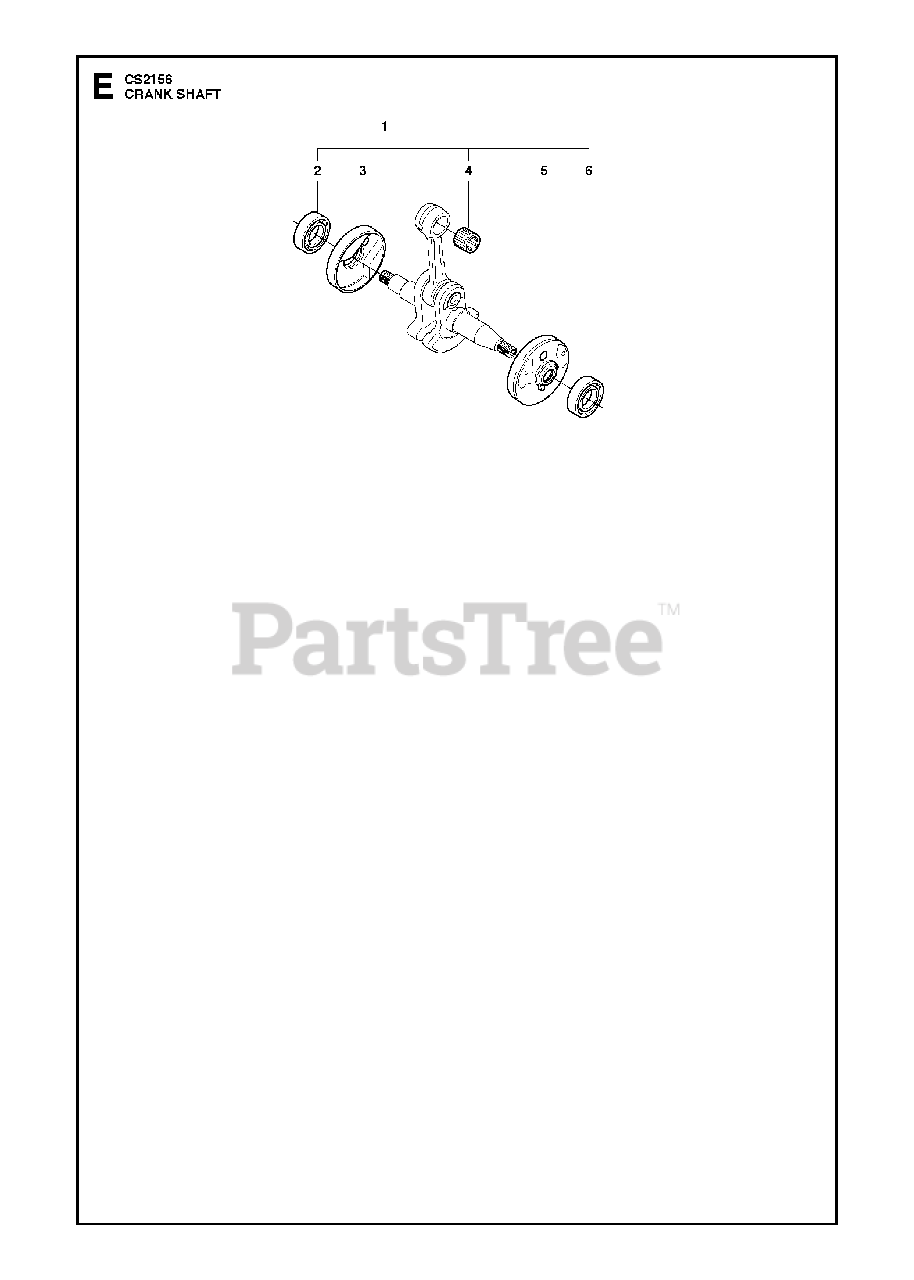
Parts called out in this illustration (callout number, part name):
1	CRANKSHAFT
2	BALL BEARING-6202-C3 SKF
3	CUP
4	SUPPORT BUSHING
5	CUP
6	BALL BEARING-6202-C3 SKF
